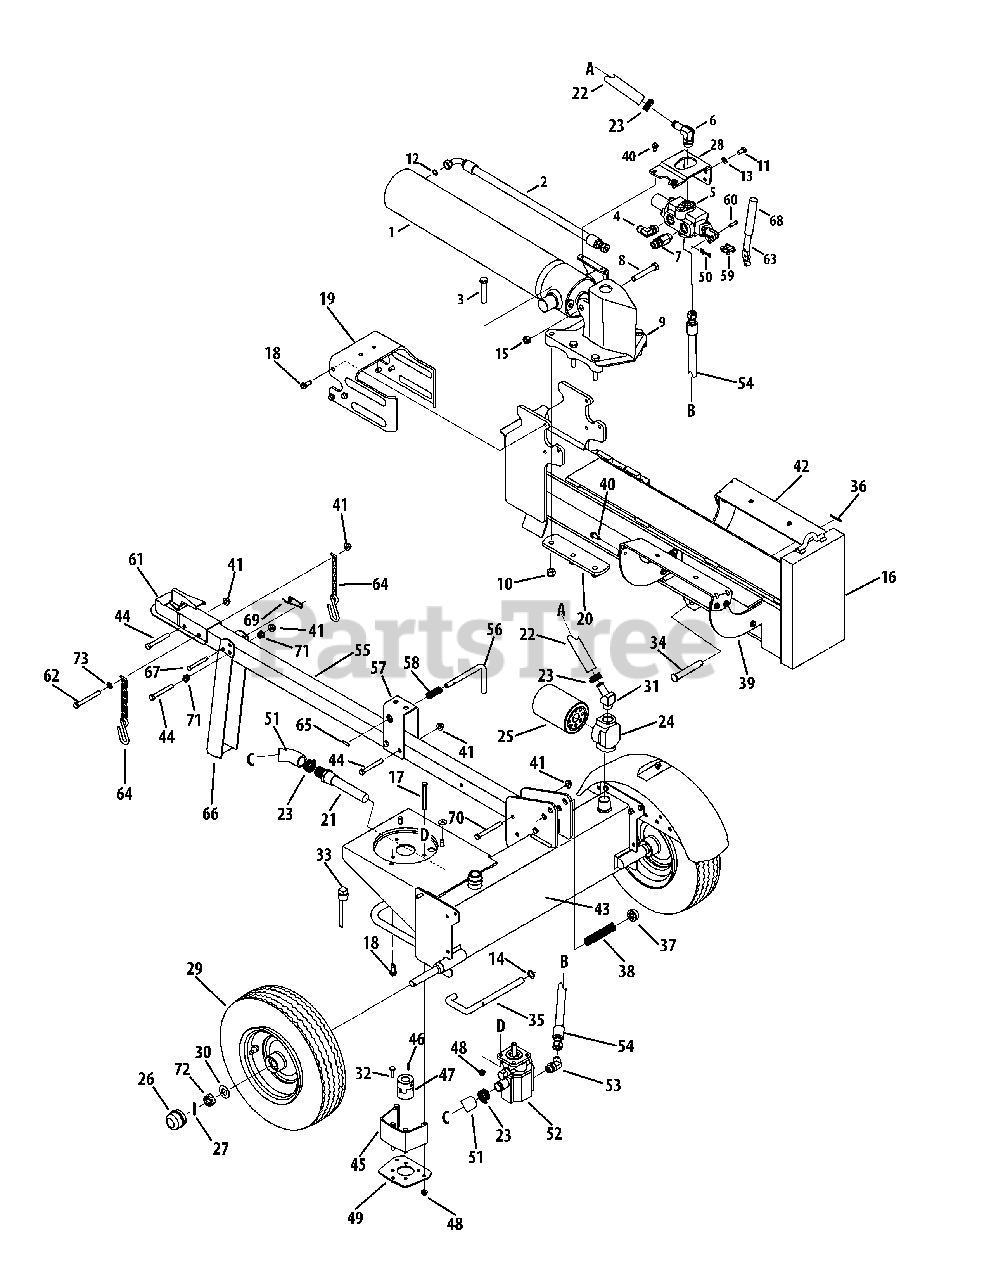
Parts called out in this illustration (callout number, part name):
1	Hydraulic Cylinder
2	Hydraulic Tube
3	Hex Cap Screw, 1/2-20 x 2.75
4	90 Degree Solid Adapter
5	Control Valve
6	Return Elbow
7	Nipple Pipe, 1/2-14
8	Hex Cap Screw, 1/2-13 x 3.25
9	Wedge Assembly
10	Hex Lock Nut, 1/2-20
11	Hex Cap Screw, 3/8-16 x .75
12	O-Ring, .419 ID x .070 Dia.
13	Lock Washer, 3/8
14	Flat Washer, .635 x.93 x.06
15	Hex Lock Nut, 1/2-13
16	Beam Assembly
17	Hex Screw, 5/16-18 x 3.25
18	Self Tapping Screw, 3/8-16 x 1.0
19	Dislodger Bracket
20	Back Plate
21	Inlet Filter
22	Return Hose, 3/4 x 44
23	Hose Clamp, 5/8
24	Filter Housing
25	Oil Filter
26	Hub Cap
27	Cotter Pin
28	Outer Valve Bracket
29	Complete Wheel Assembly
29	Dust Seal
29	Roller Bearing
30	Flat Washer, .760 x.500
31	Hydraulic Fitting, 1 1/16 Orb x .75
32	Hex Screw, 5/16-18 x 1.00
33	Vented Dipstick
34	Clevis Pin
35	Lock Rod
36	Cotter Pin
37	Push Cap
38	Compression Spring
39	Log Tray Bracket
40	Hex Washer Screw, 5/16-18 x .750
41	Flange Lock Nut, 3/8-16
43	Frame Assembly
44	Hex Bolt, 3/8-16 x 3
45	Coupling Shield
46	Square Key, 3/16" x .75
47	Log Splitter Coupling
47	Coupling, .500
47	Coupling, .875
47	Spider Bushing
47	Set Screws
48	Flange Lock Nut, 5/16-18
49	Rear Coupling Support Bracket
50	Cotter Pin, Bow Tie
51	Hose
52	Gear Pump
53	45 Degree Elbow Fitting
54	High Pressure Hydraulic Hose
55	Tongue Assembly
56	Latch Rod
58	Compression Spring
59	Valve Handle Link
60	Clevis Pin
61	Hitch Coupling Assembly
62	Hex Cap Screw, 3/8-16 x 3.50
63	Hydraulic Valve Control
65	Spiral Pin
66	Jack Stand
67	Clevis Pin
69	Spring Pin
70	Hex Cap Screw, 3/8-16 x 3.50
71	Plastic Bushing, .380 ID
72	Slotted Nut, 3/4-16
73	Flat Washer, .375 x.738 x.063
